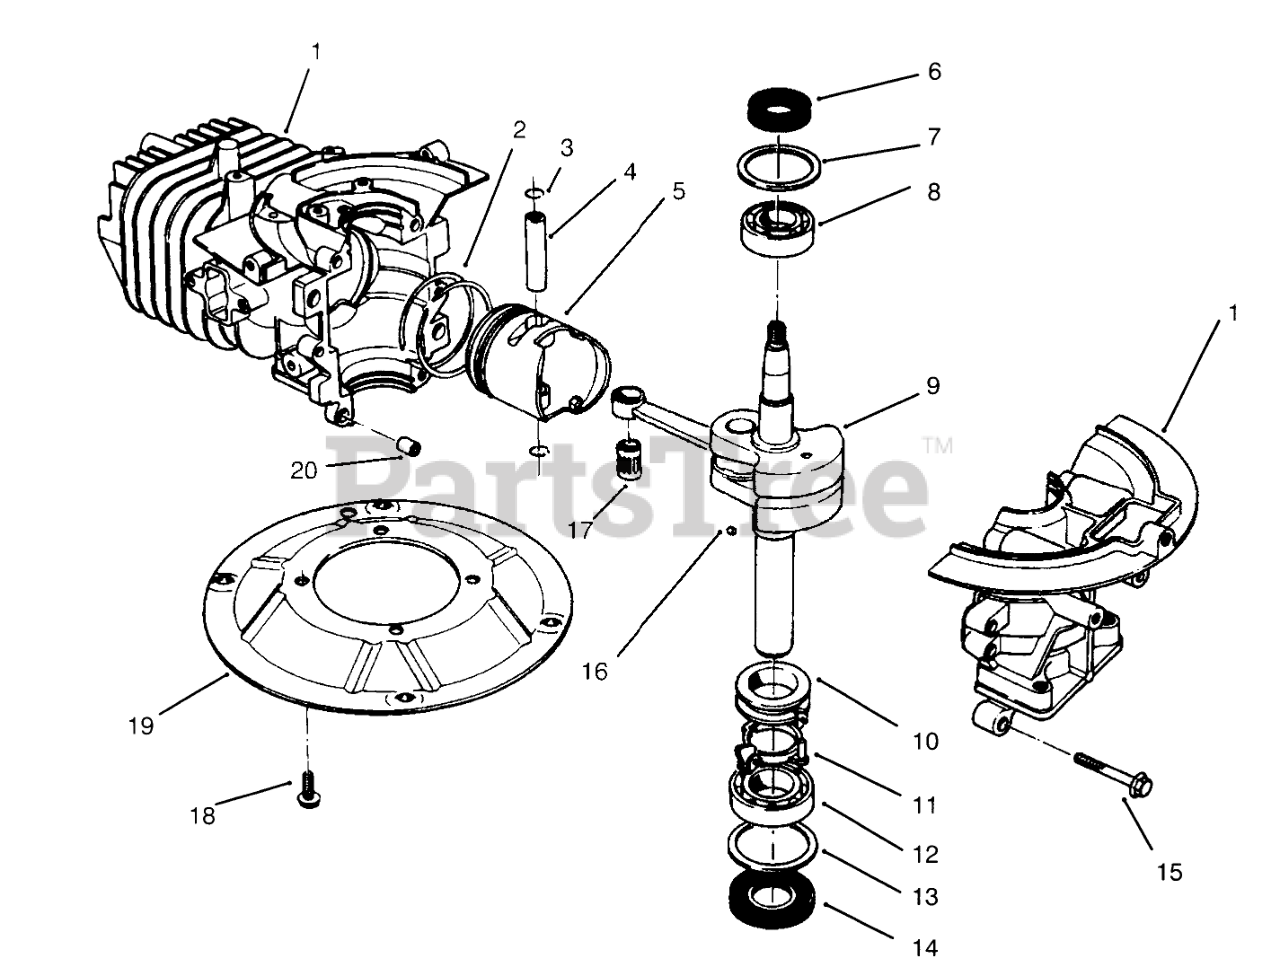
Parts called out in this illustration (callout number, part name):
1	CRANKCASE
2	RING SET
4	PIN-PISTON
5	PISTON
6	OIL SEAL
7	WASHER-UPPER
8	BEARING-UPPER
9	CRANKSHAFT
10	SPACER
11	BRACKET
12	LOWER BRG
13	WASHER-LOWER
14	SEAL-OIL
17	BEARING
19	PLATE-MOUNTING
